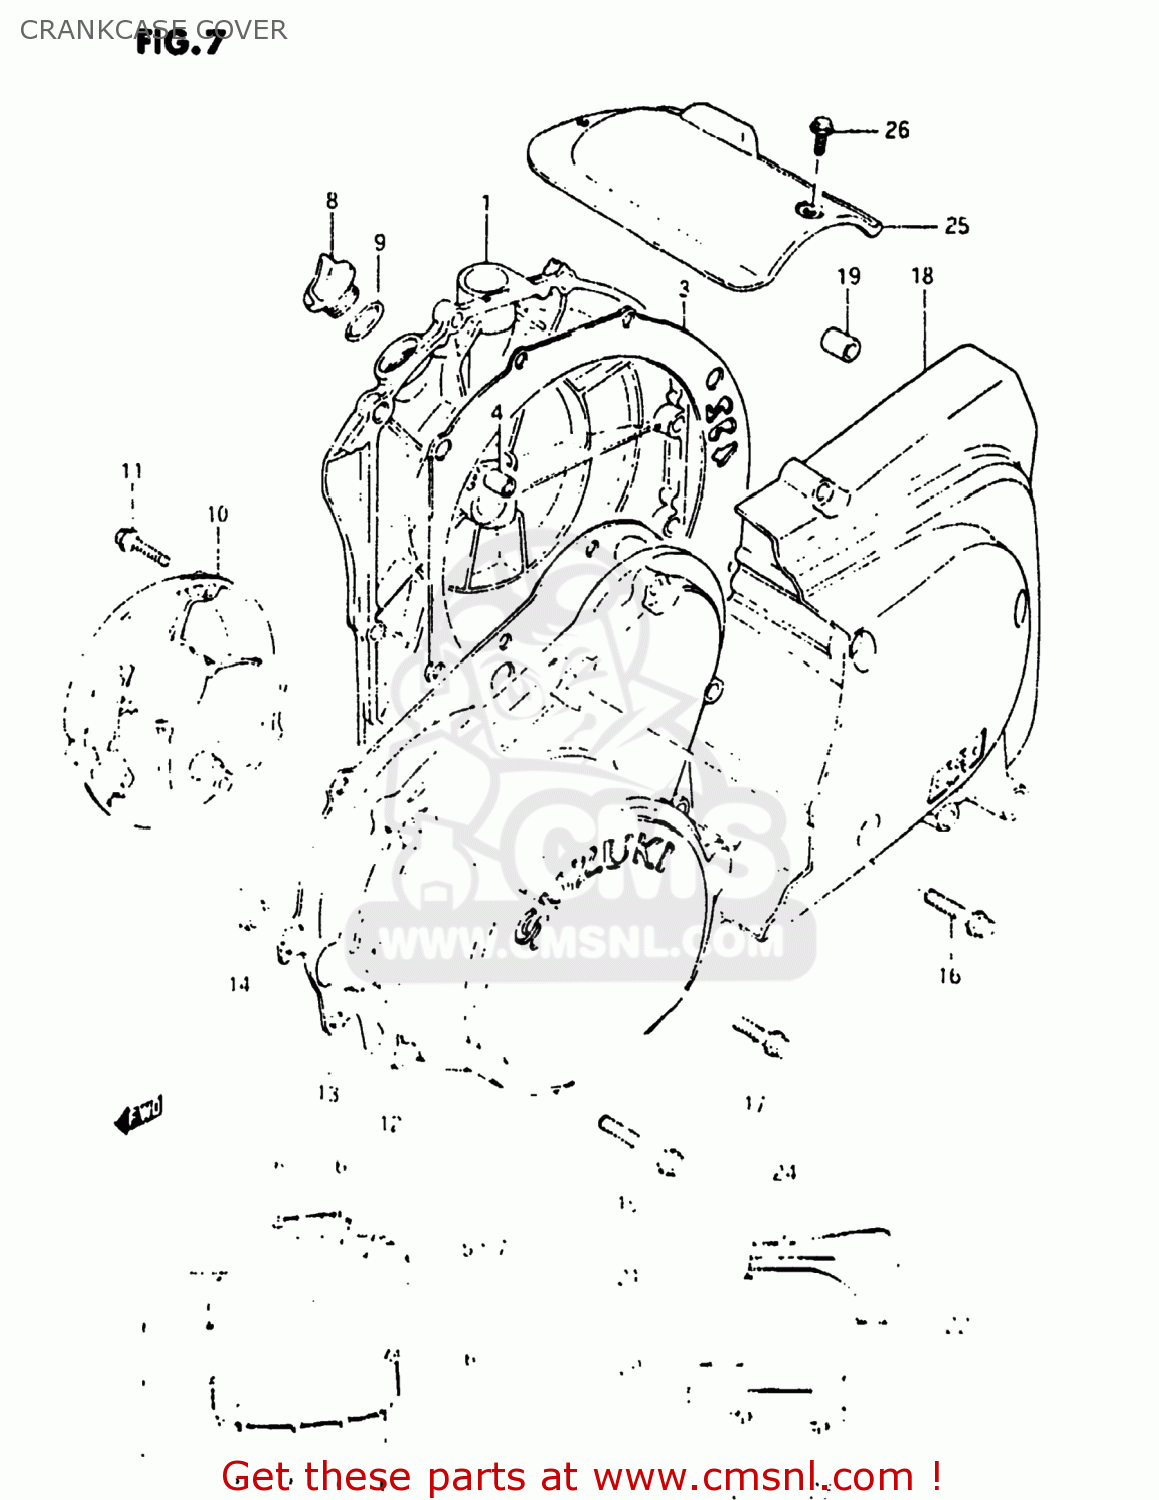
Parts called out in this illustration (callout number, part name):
1	COVER,CLUTCH
2	LENS,OIL LEVEL CHECK
3	GASKET,CLUTCH COVER (MCA)
4	PIN
5	BOLT
6	BOLT
7	WASHER
8	PLUG
9	O RING(D:3.1,ID:16.8)
10	COVER,CONTACT BREAKER
11	BOLT
12	COVER,MAGNETO
13	GASKET,MAGNETO COVER (MCA)
14	PIN
15	BOLT
16	BOLT
17	BOLT
18	COVER,ENGINE SPROCKET
19	PIN
20	BOLT
21	BOLT
22	BOLT
23	BOLT
24	BOLT
25	COVER,STARTER MOTOR
26	BOLT
